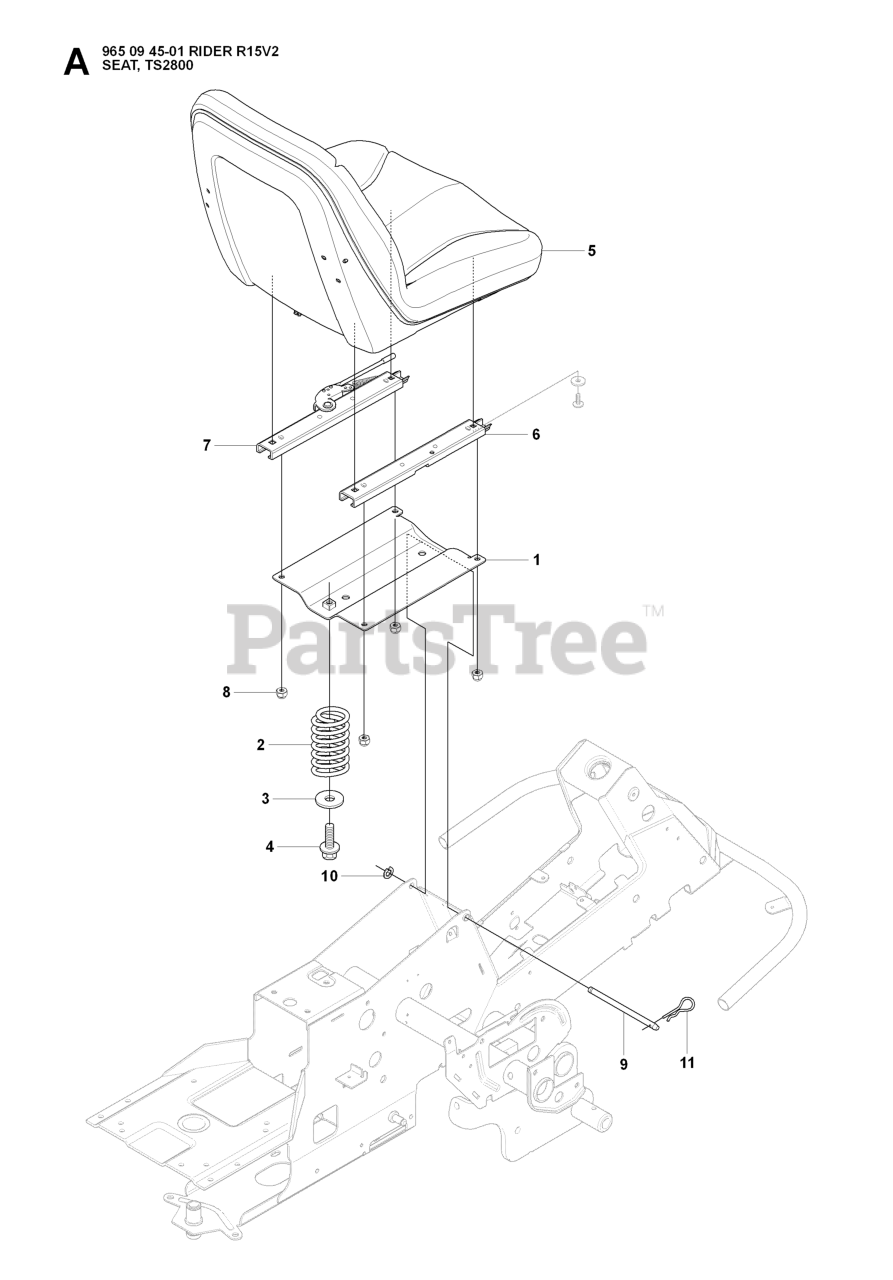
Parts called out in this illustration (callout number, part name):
2	SEAT SPRING
4	Screw M10x25
5	SEAT
8	LOCKNUT M8
10	RETAINING RING SGA 10
